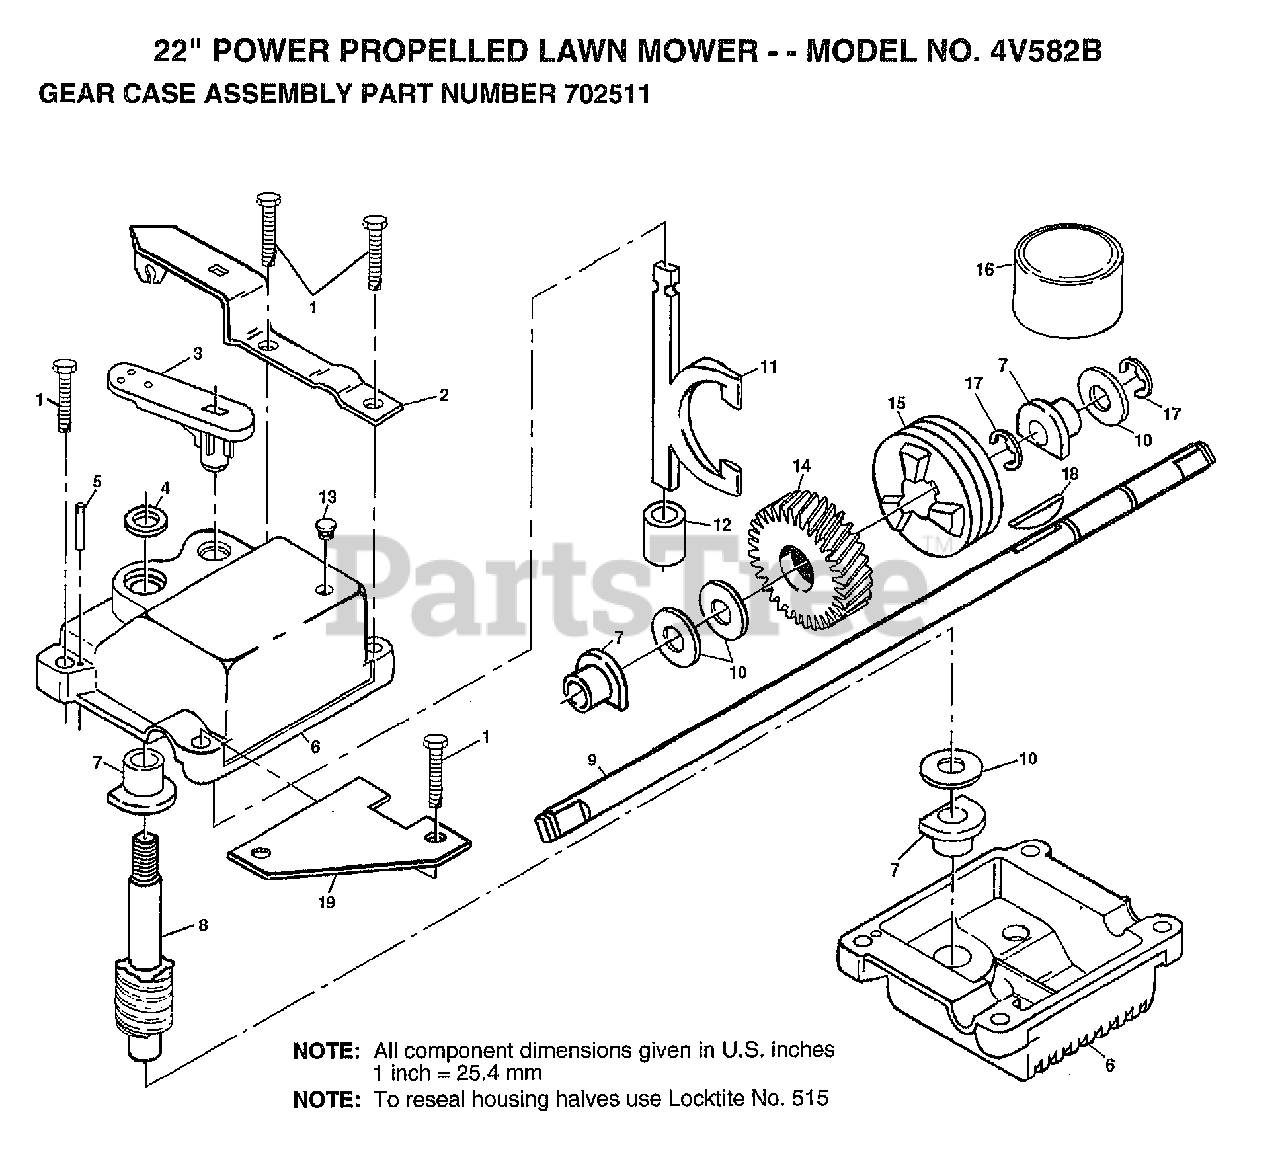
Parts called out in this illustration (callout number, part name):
1	SCREW.1/4-20
3	SHIFTER
4	SEAL
5	DRIVE LOK PIN
6	GEARCASE KIT
7	BEARING
8	SHAFT.WORM
9	SHAFT.DRIVE
10	THRUST WASHER
11	CLUTCH YOKE
12	BUSHING.GEAR BOX
13	PLUG PM
14	GEAR.HELICAL
15	CLUTCH JAW
17	RING T
18	HI PRO KEY
